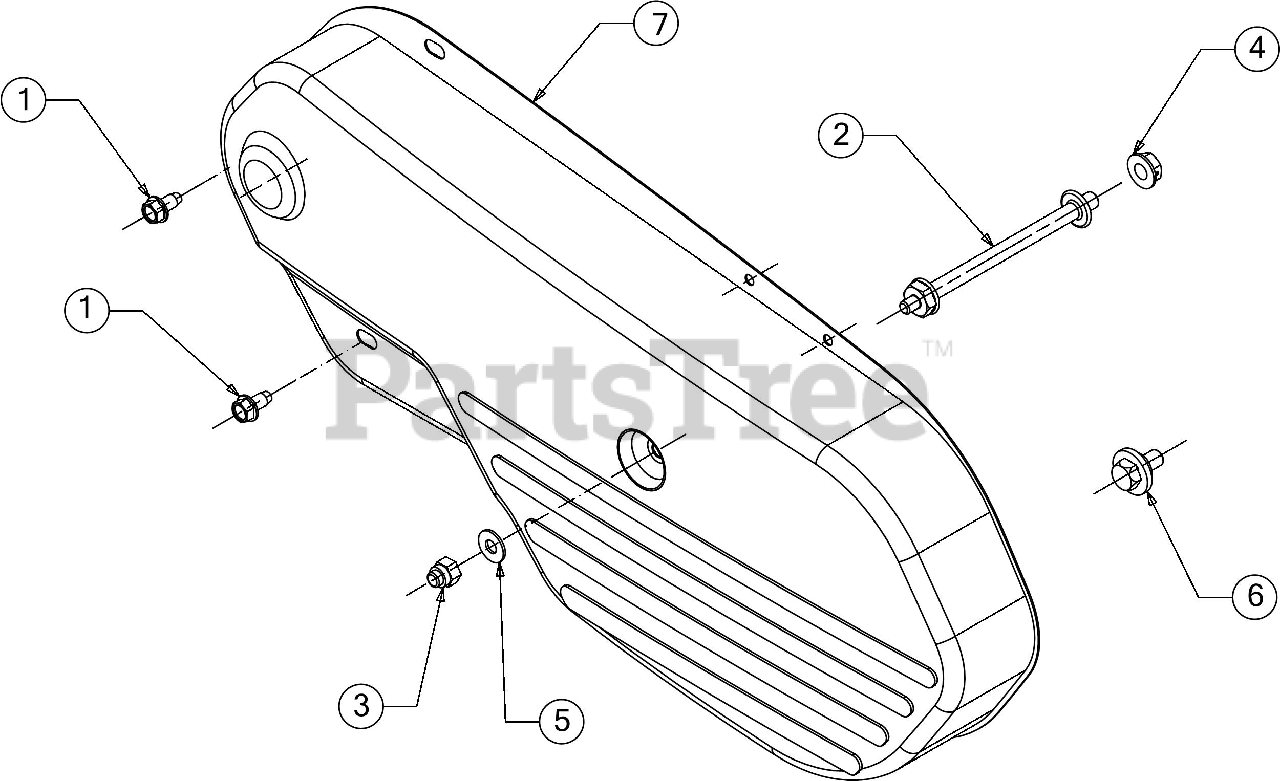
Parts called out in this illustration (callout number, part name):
1	SCREW 1/4-20 X.500
2	BELT COVER BOLT
3	HEX ACORN NUT
4	HEX FLANGE NUT
5	FLAT WASHER .271:.630:.065
6	SHOULDER SCREW .560X.165: 5/16-18
7	BELT COVER W/O REV.
